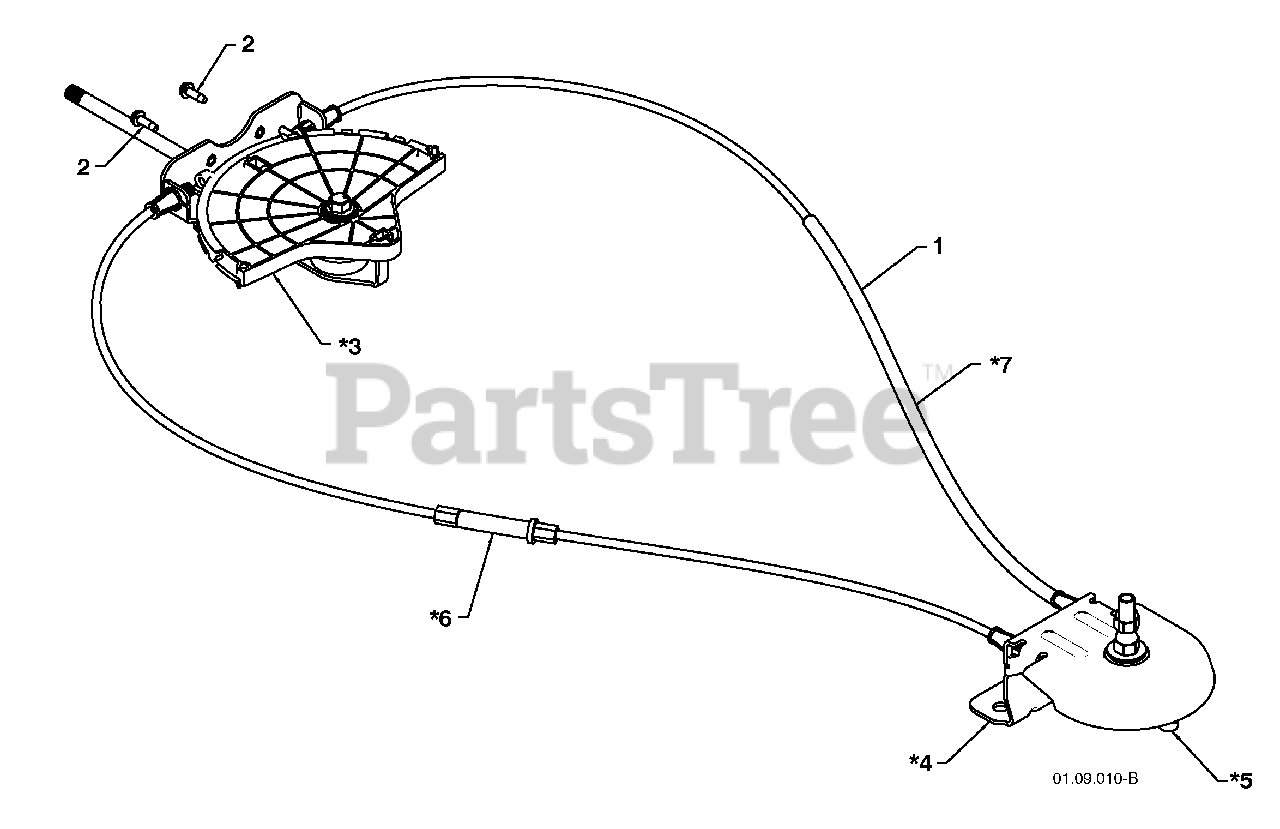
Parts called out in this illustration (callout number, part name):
1	LEVER/CABLE ROTATOR ASSEMBLY
2	SCREW 10-24 X .625
3	ROTATOR HEAD
4	ROTATOR PIVOT BRACKET
5	PULLEY PIVOT
6	CABLE ASSEMBLY ADJUSTABLE
7	CABLE ASSEMBLY HEAT SHIELD
